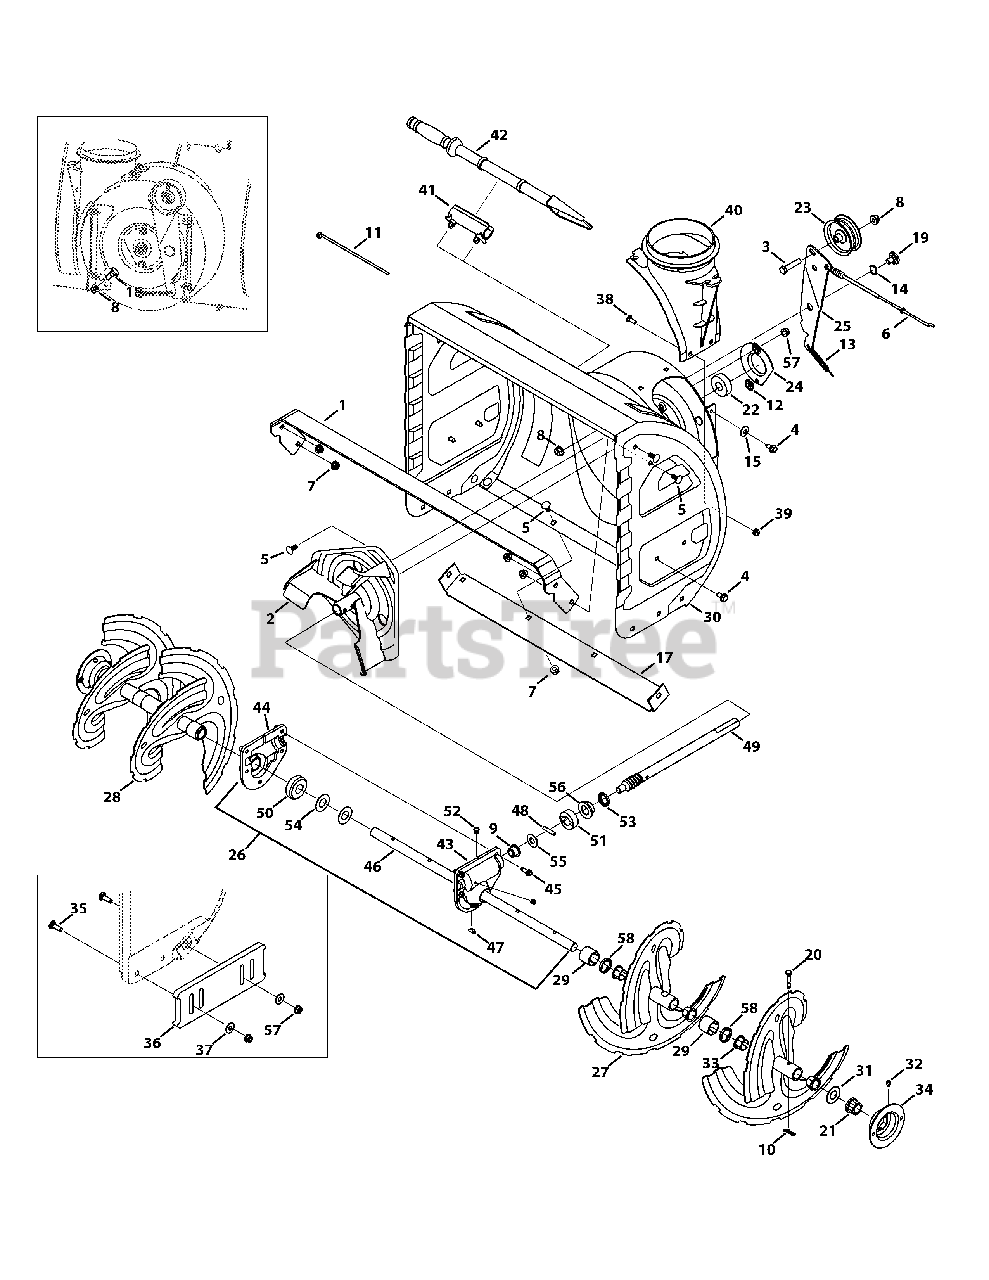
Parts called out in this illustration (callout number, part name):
1	Housing Support Bracket, 30"
2	Impeller Assembly
3	Hex Bolt, 3/8-16 x 1.75
4	Screw, 5/16-18 x .750
5	Carriage Bolt, 5/16-18 x .750
6	Auger Clutch Cable
7	Flange Lock Nut, 5/16-18
8	Flange Lock Nut, 3/8-16
9	Flange Bearing, .50 x .75 x .59
10	Bow Tie Cotter Pin
11	Cable Tie
12	Push-On Nut, .25 Dia.
13	Extension Spring, .38 OD x 4.59
14	Wave Washer, .625 x .885 x .0175
15	Bell Washer, .340 x .872 x .060
16	Bell Washer, .340 x .872 x .060
17	Shave Plate, 28"
18	Shoulder Screw, 3/8-16 x .496 x .336
19	Shoulder Screw, 3/8-16 x .625 x .17
21	Hex Flange Bearing
22	Flange Ball Bearing, .75 x 1.85
23	Flat Idler Pulley
24	Bearing Housing
25	Auger Idler Bracket
26	Gearbox Assembly, Auger, 28"
27	Spiral Assembly - LH
28	Spiral Assembly - RH
29	Spacer, 1.25 x .75 x 1.00
30	Auger Housing, 28"
31	Flat Washer, .76 x 1.49 x .06
32	Drive Lube Fitting
33	Flange Bushing, .800 x .910
34	Bearing Housing
35	Spacer, Carriage, 5/16-18 x 1.00
36	Deluxe Polymer Skid Shoe - Blue
37	Washer, Flat, .349 x .879 x .063
38	Carriage Screw, 1/4-20 x 0.75
39	Flange Lock Nut, 1/4-20
40	Chute Adapter
41	Clean-out Tool Mtg. Bracket
42	Clean-Out Tool
43	Housing Assembly - RH
44	Housing Assembly - LH
45	Screw, 1/4-20 x 0.75
46	Axle, Auger, 28"
47	Hi-Pro Key
48	Dowel Pin, .25OD x 1.25
49	Worm Shaft
50	Worm Gear, 20T
51	Thrust Collar
52	Plug, 1/4 x .437
53	Oil Seal, .75 x 1.131 x .188
54	Flat Washer, .76 x 1.5
55	Flat Washer, .51 x 1.12 x .06
56	Flange Bearing, .75 x 1.00 x .59
57	Hex Lock Nut, 5/16-18
58	Spacer, 1.25 OD x .75 ID x 3/16 Lg
